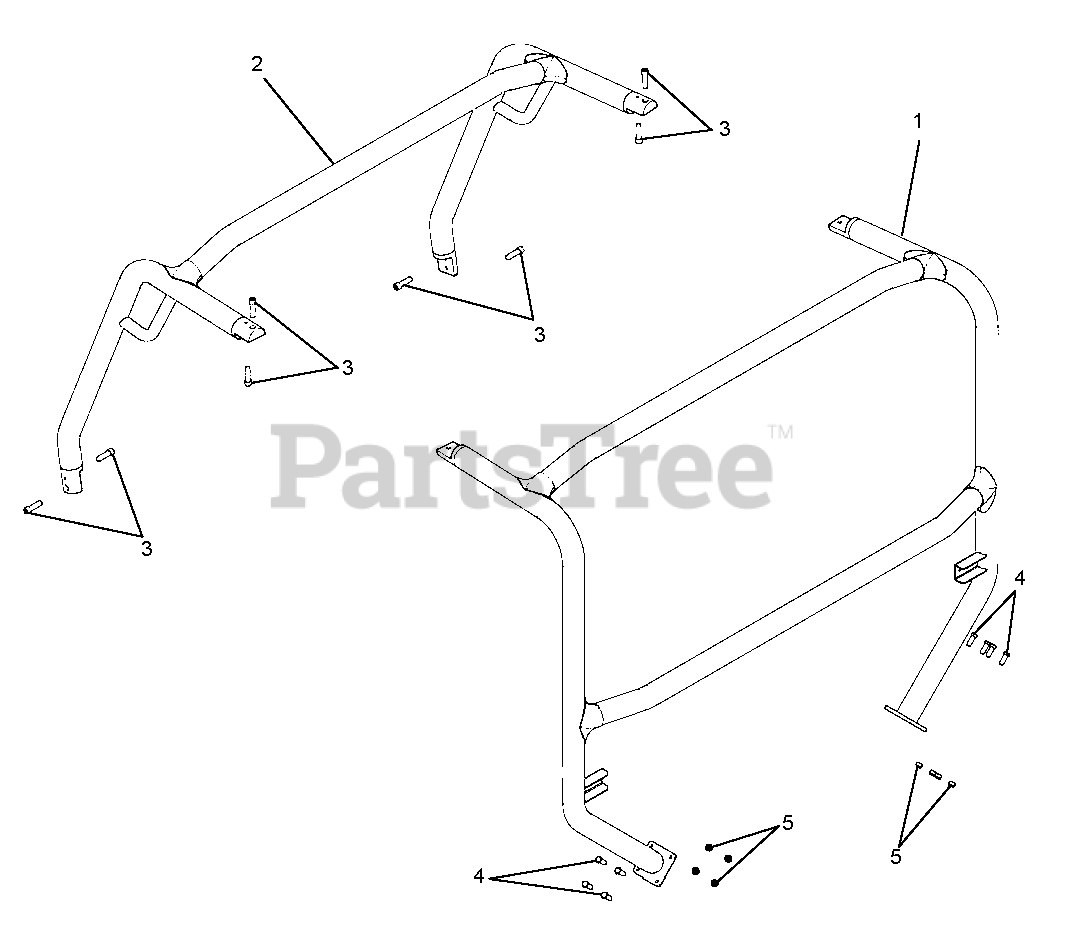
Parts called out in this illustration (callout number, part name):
1	ROPS WELDMENT, TREKER REAR
2	ROPS WELDMENT, TREKER FRONT
3	HSHCS 3/8-16 X 1 1/2 GR5 (Apply Loc-Tite¨)
4	BOLT, HEX 5/16-18 X 1 GR5 (Apply Loc-Tite¨)
5	NUT, NYLON LOCK 5/16-18 YWZC
